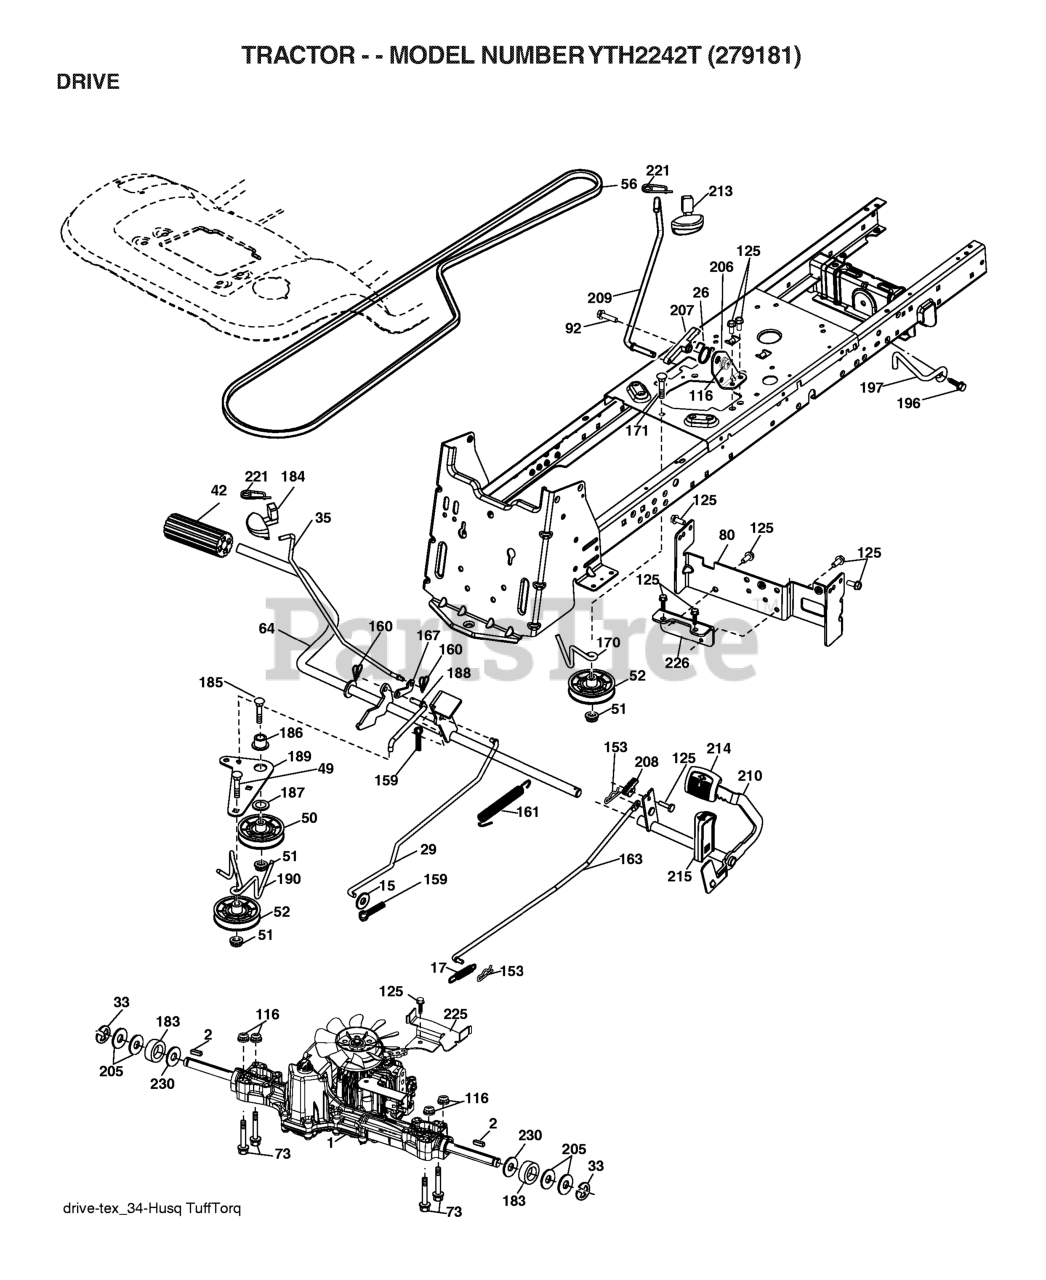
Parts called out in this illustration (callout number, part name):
1	TRANSAXLE, TUFFTORQ K46
2	SQUARE KEY
15	WASHER
17	SPRING.BRAKE.K46
26	SPRING.RETURN.CRUISE
29	ROD.BRAKE.K46
35	ROD.BRAKE.PARKING.GT.H
42	PEDAL COVER T
50	IDLER.FLAT.910.OFFSET
51	NUT LOCK FLG 3/8-16 UNC
52	IDLER.V-GROOVE.910.OFFSET
56	V-BELT.MOWER.92.40.42/K46
64	SHAFT.ASM.PEDAL.BRK.CNTR
73	BOLT HEX 5/16-18 GR 5
80	STRAP.TORQUE.HG3000/K46
92	BOLT
116	NUT LOCK HEX FLANGE 5/16-18
125	SCREW
153	RETAINER M
159	COTTER PIN
160	RETAINER CLIP
161	SPRING.RETURN.CLUTCH.2006
163	ROD.CONTROL.PEDAL.K46
167	LATCH.BRAKE.SPRING
170	KEEPER.V-IDLER.CENTER.
183	SPACER AXLE
184	HANDLE.PARKG.BRK.HUSQ X667
186	SPACER.RETAINER
187	WASHER 12/32X2X10GA
188	RP.LINK.CLUTCH.GROUND.DRIVE
189	BELLCRANK.GROUND.DRIVE.TEX.
190	KEEPER.BELLCRANK.DRIVE
196	SCREW 3/8-16X1
197	LINK.CLUTCH.ANIT-ROTAT
206	BRKT.MOUNT.LATCH.CRUIS
207	LATCH.CONTROL.CRUISE
208	GEAR.SECTOR.CONTROL.CR
209	ROD.CONTROL.CRUISE.GT.
210	ROCKER.ASM.PEDAL.CONTR
213	KNOB.CONTROL.CRUSIE.HU
214	PEDAL.FORWARD.TEX.GT.4
215	PEDAL.REVERSE.TEX.GT.4
221	RETAINER.SPRING.CLIP.H
225	KEEPER.BELT.TRANSAXLE.K46
226	BRACKET.MOUNT.TORQUE.K46.TLT
230	WASHER.HARDENED
